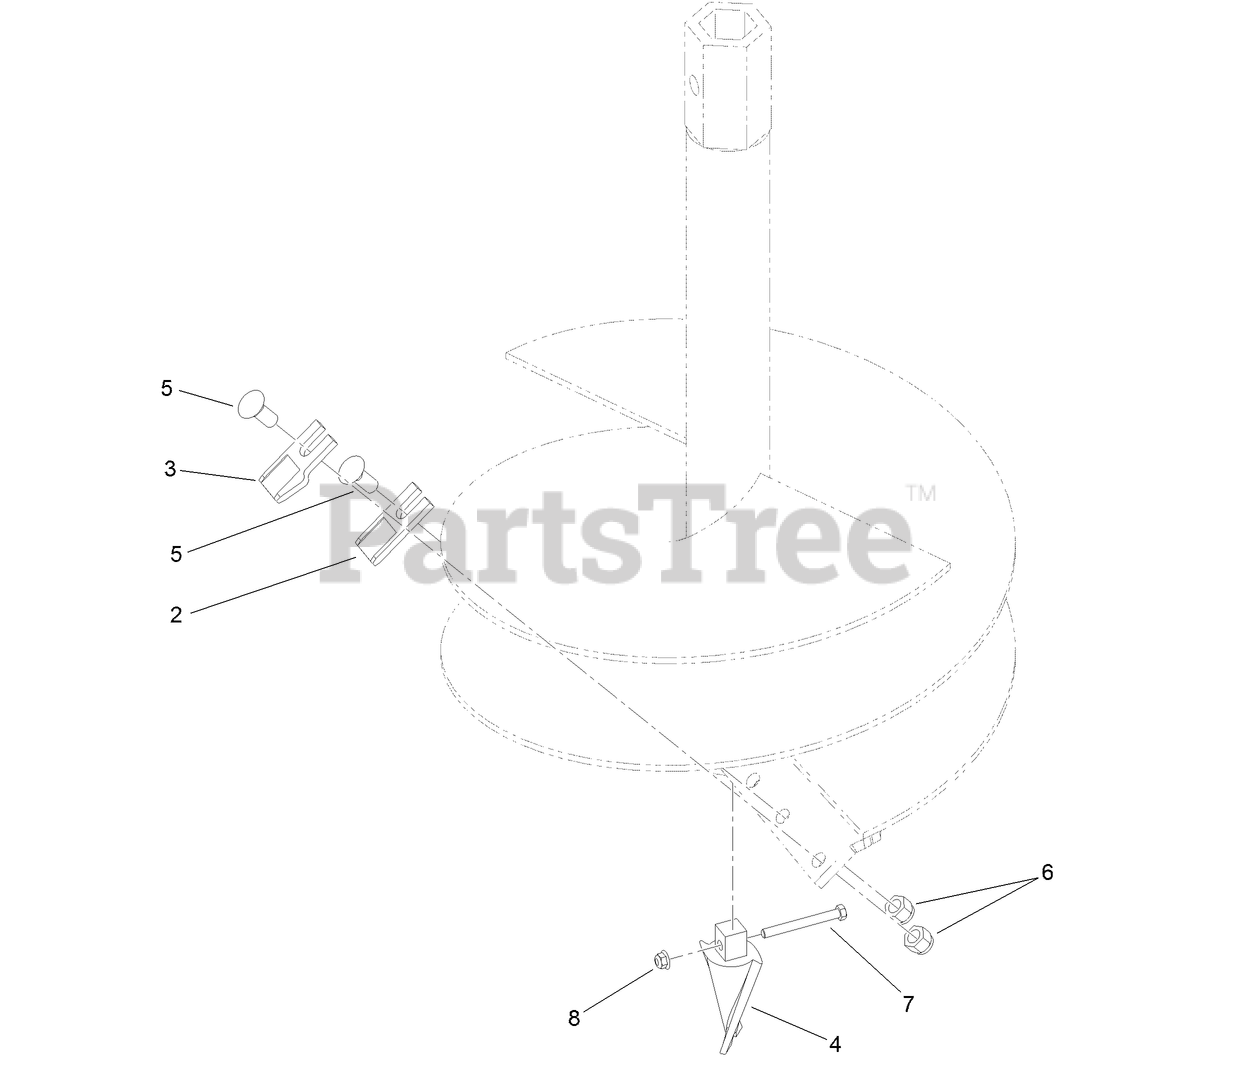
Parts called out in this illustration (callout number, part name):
2	TOOTH-AUGER, WISDOM (INSIDE)
3	TOOTH-AUGER, WISDOM (OUTER)
4	TOOTH-FISHTAIL, STANDARD
5	SCREW-CARRIAGE
6	NUT-LOCK, NI
7	SCREW-HH
8	NUT-HF, NI
